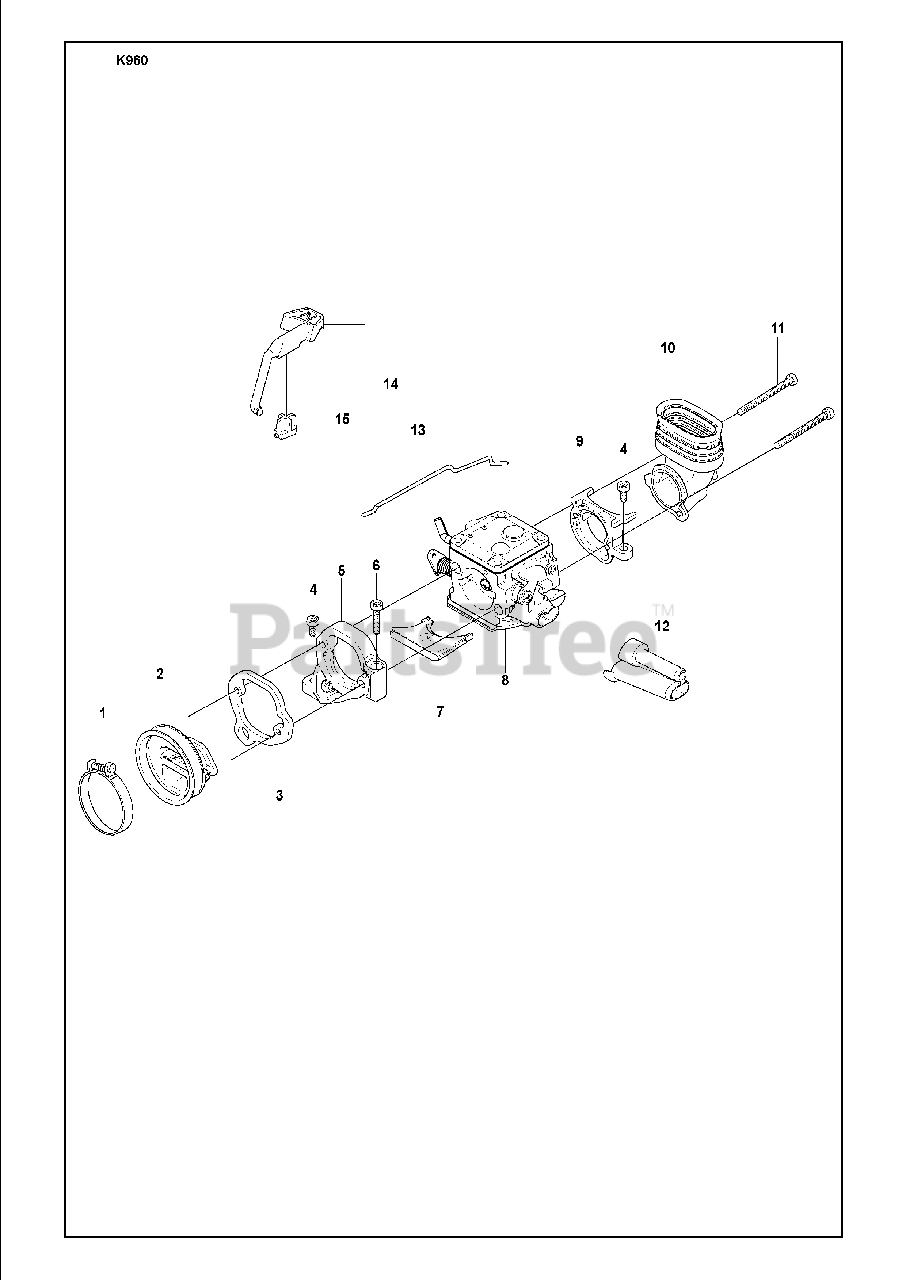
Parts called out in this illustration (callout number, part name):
1	Hose Clamp
2	Inlet Pipe
8	Carburettor
10	Inlet Bend
11	Screw
12	Chisel Guide
13	Throttle Rod
14	Choke
15	Wear Protection
